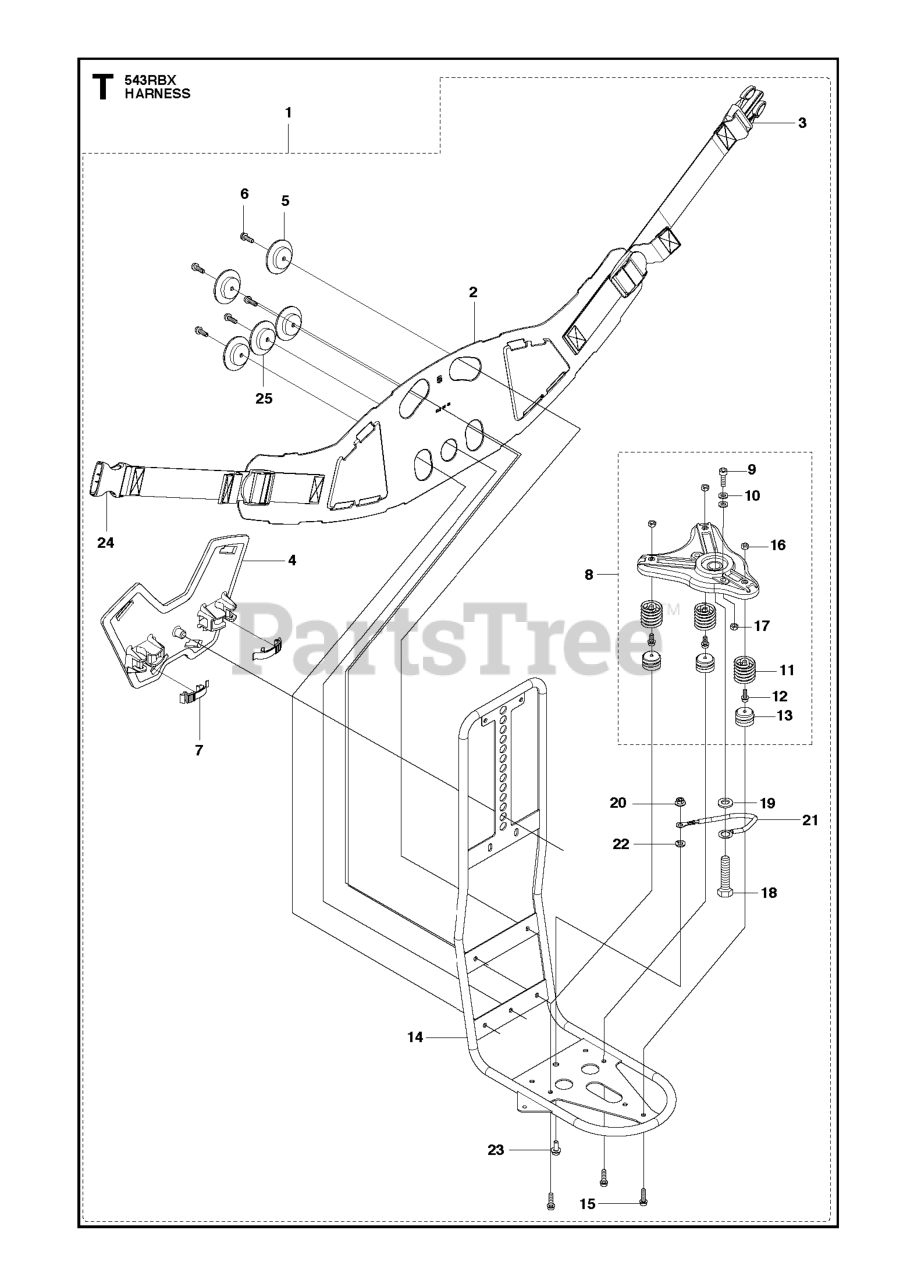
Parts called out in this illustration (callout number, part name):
3	BUCKLE, MALE
9	SCREW IHSCM
10	WASHER - M6
19	WASHER, M10 x 1.6
24	BUCKLE, FEMALE
